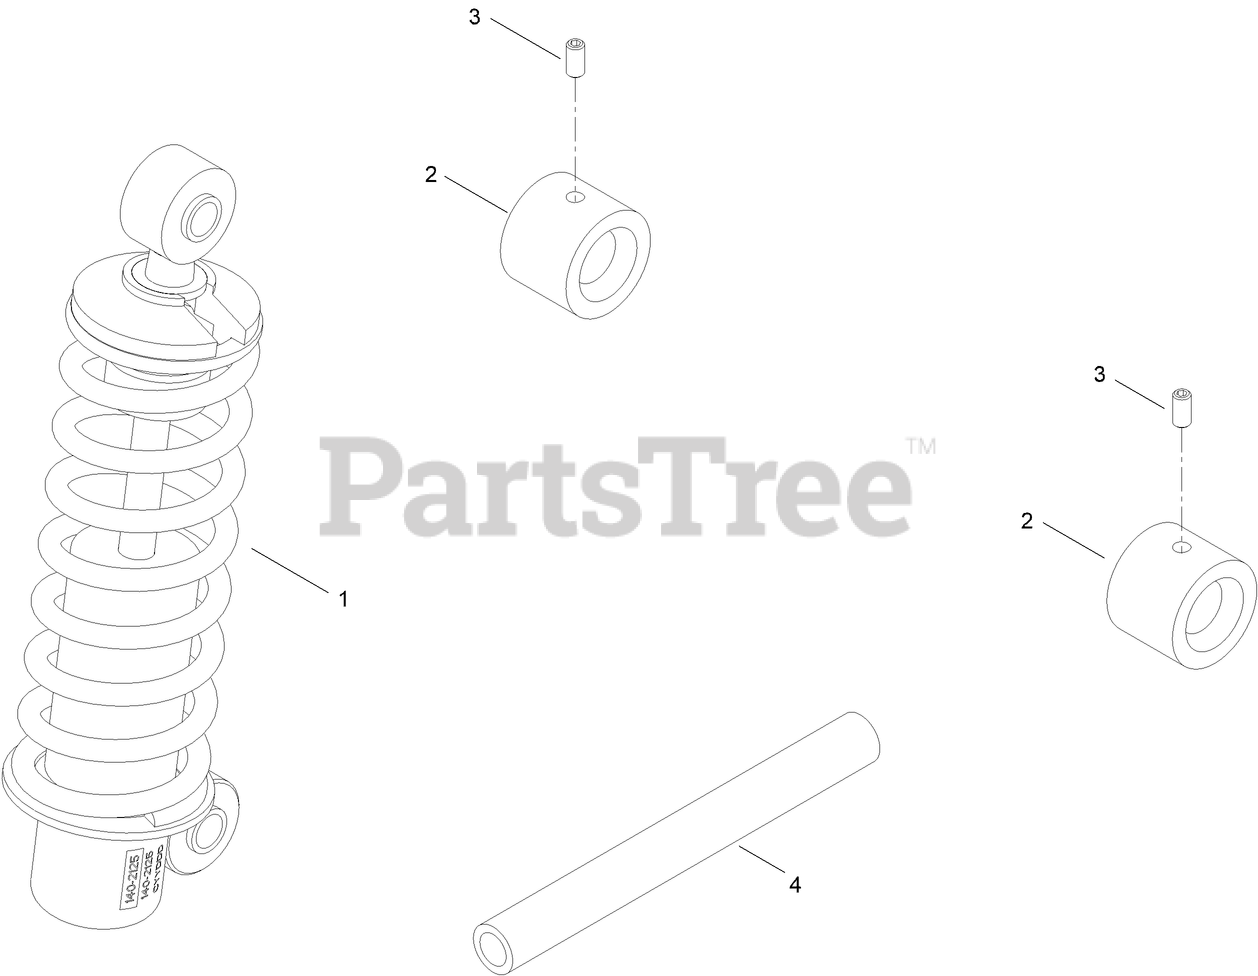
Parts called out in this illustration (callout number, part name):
1	SHOCK/SPRING ASM
2	SPACER - SPRING
3	SCREW-SET, HSH
4	TUBE-SPRING LIFT
